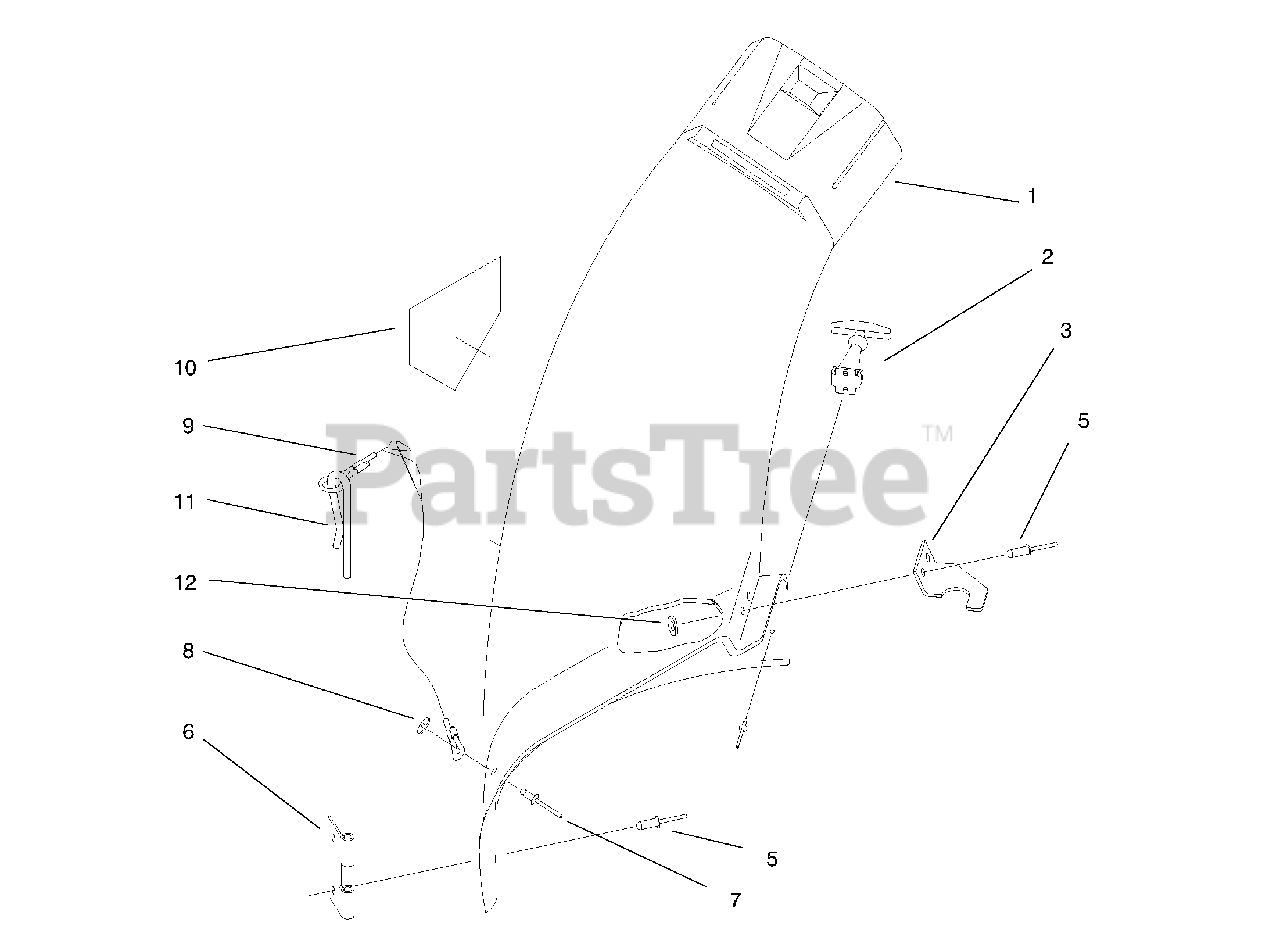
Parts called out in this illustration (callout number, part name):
1	Elbow-Bagger
2	Latch-Flexible Draw
3	Latch-Bagger Elbow
4	Rivet-Pop
5	Rivet-Pop
6	Bracket-Mounting Chute
7	Rivet-Pop
8	Washer-Flat
10	Decal-Danger
11	Pin-Lock, Chute
12	Washer-Flat
